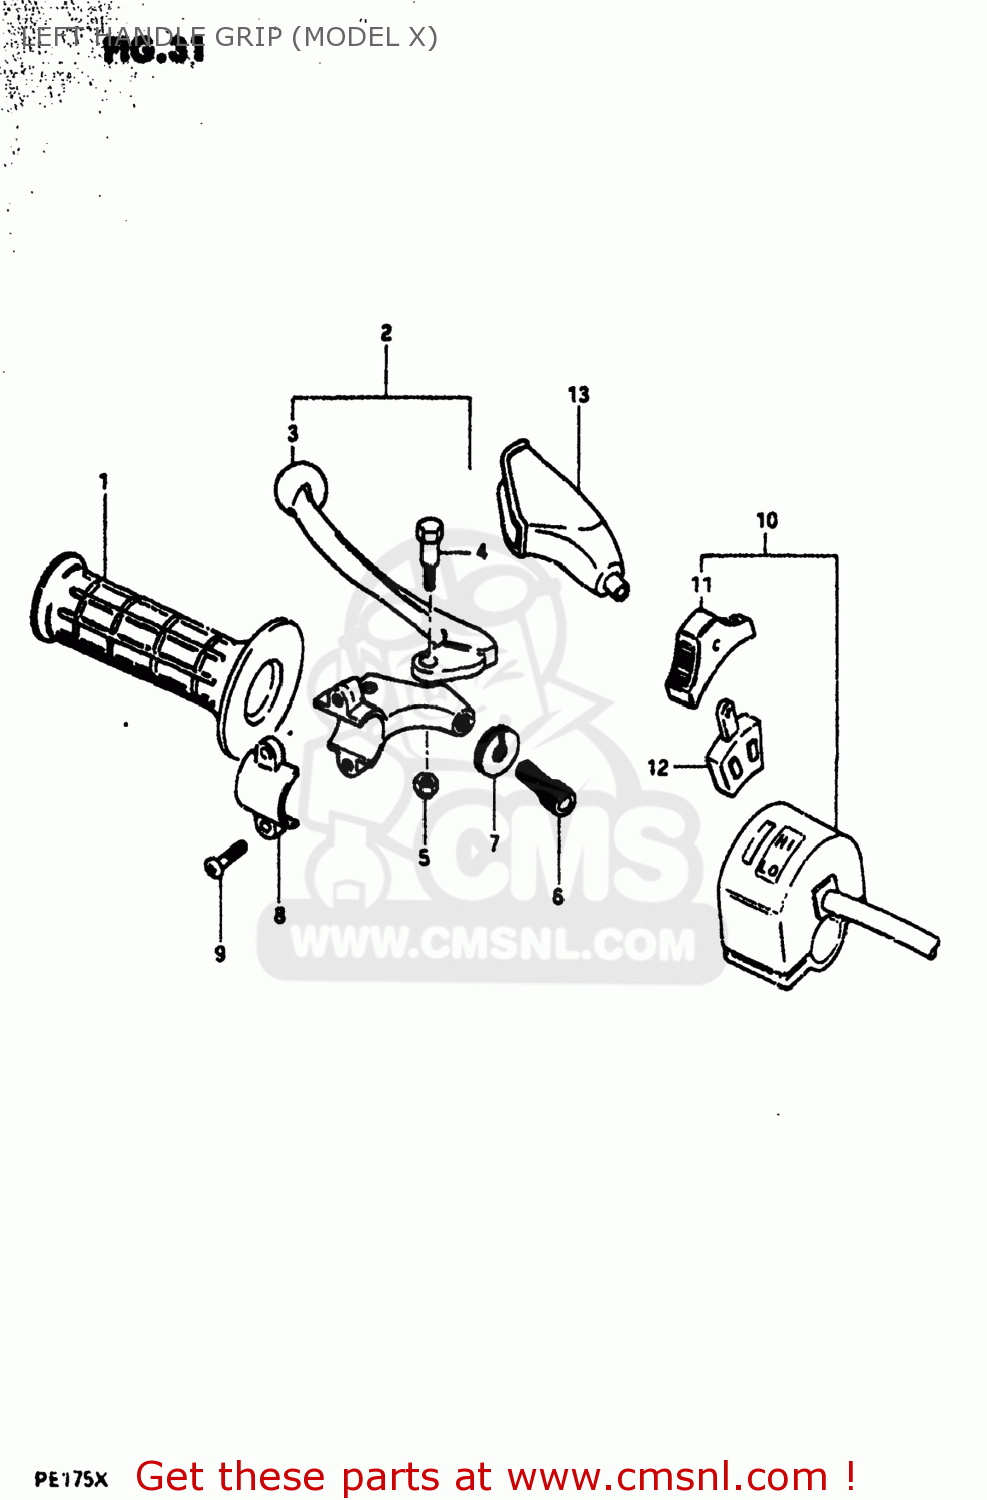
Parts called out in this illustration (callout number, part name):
1	GRIP,LEFT
2	LEVER ASSEMBLY
3	LEVER,CLUTCH
4	BOLT,LEVER
5	NUT 6MM
6	ADJUSTER,CABLE
7	NUT,CABLE ADJUSTER
8	BRACKET,LEVER
9	SCREW
10	SWITCH,DIMMER
11	KNOB,LIGHTING & DIMMER
12	BLOCK,LIGHTING/DIMMER
13	COVER,CLUTCH LEVER
